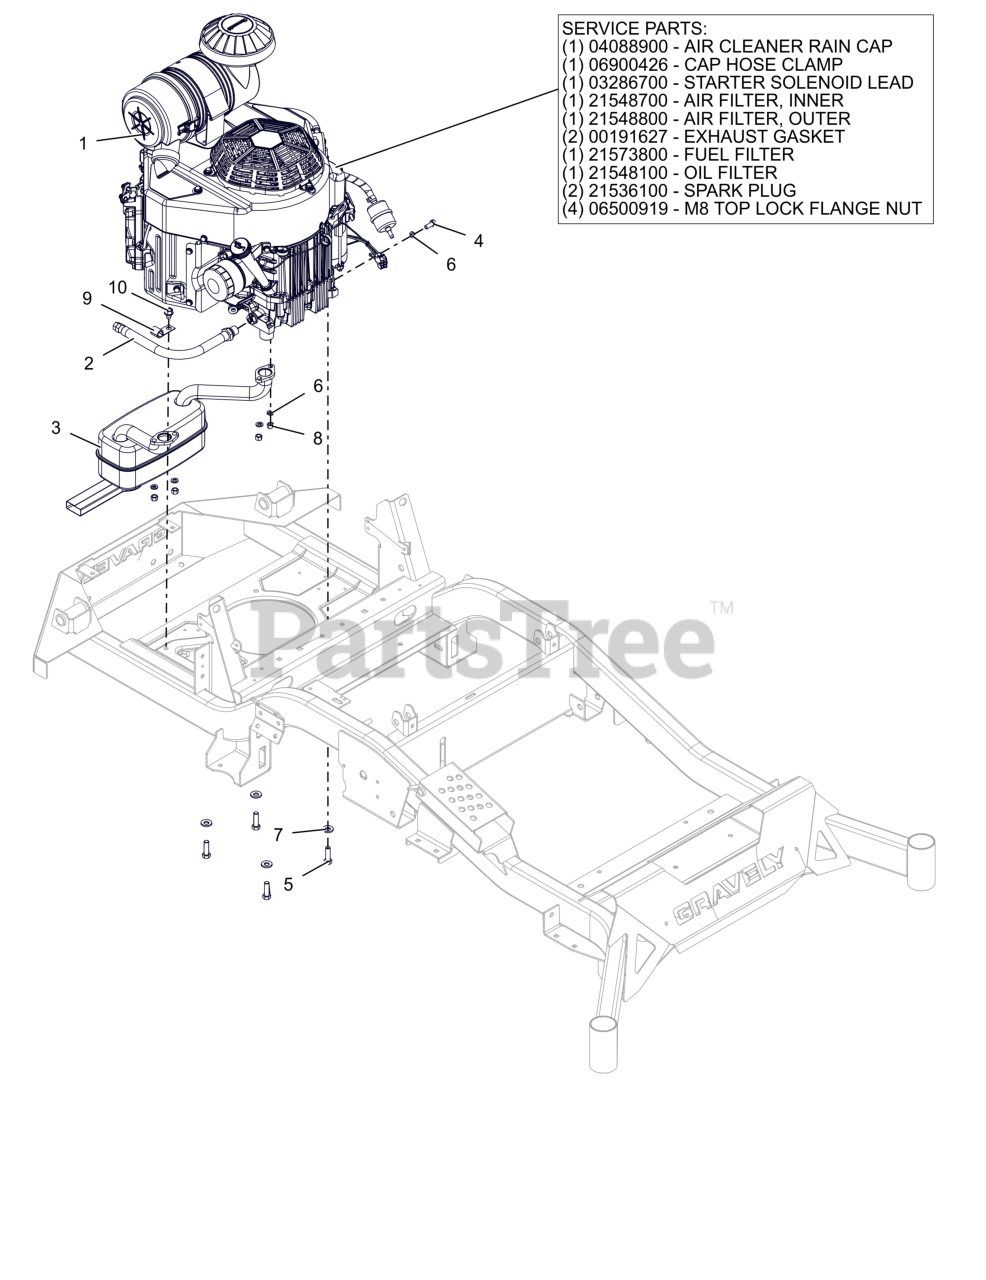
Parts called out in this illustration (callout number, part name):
1	ENGINE, KAWASAKI
1	CAP, KAW 11065-7025
1	CLAMP, HOSE #36 SS 1.813-2.75
1	LEAD - STARTER SOLENOID
1	FILTER, INNER - KAW
1	FILTER, OUTER
1	GASKET, MUFFLER S/O
1	FUEL FILTER
1	OIL FILTER, KAWASAKI FR
1	PLUG, SPARK
2	HOSE, OIL DRAIN
3	MUFFLER, KAWASAKI
4	BLT, HEX M8-1.25X20 G8.8 ZCC
5	BLT, HEX .38-16X1.25 G5 ZCC NT
6	WSHR,LK-REG .312X.078 ZCC
7	WASHER, 3/8" SPRING DISC
8	NUT-LK-TOP-FLG M8 ZCC
10	SCR,TAP .375-16X.50 HWH TR ZCC
